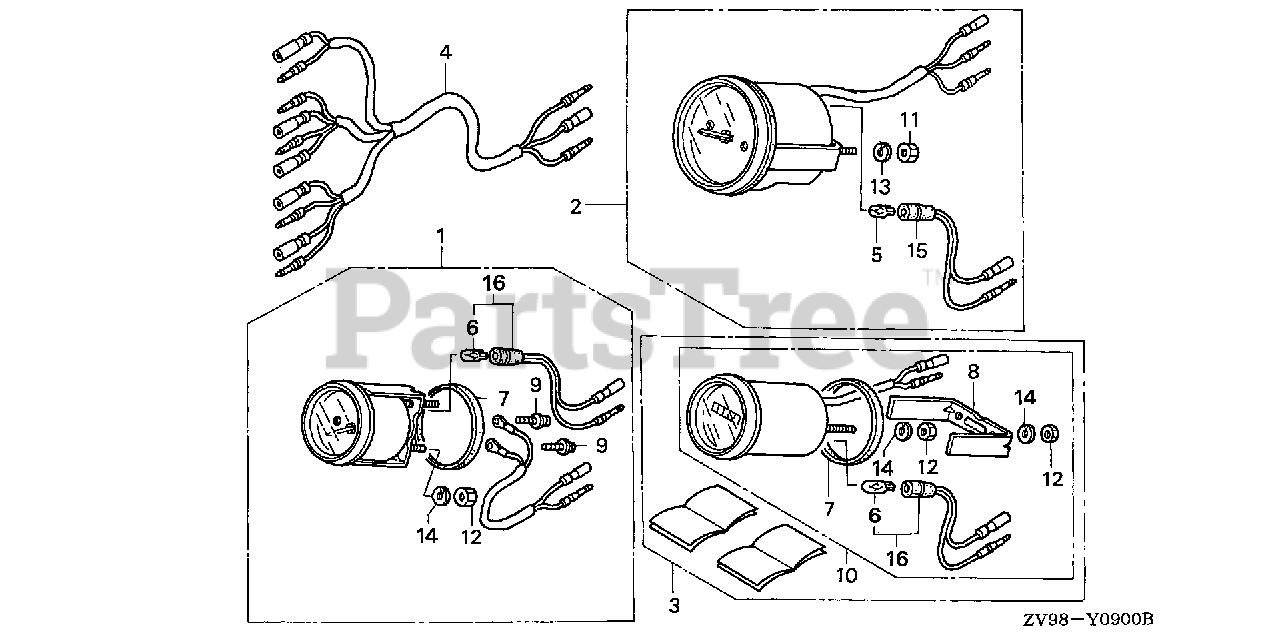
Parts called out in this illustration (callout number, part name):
1	METER KIT, VOLT
1	METER KIT, VOLT (B)
2	METER KIT, TACHO (NOT AVAILABLE)
2	METER KIT, TACHO (B)
3	METER KIT, HOUR (NA USE ALT:39700-ZW5-000ZA)
3	METER KIT, HOUR (B) (NA USE ALT:39700-ZW5-000ZA)
4	HARNESS ASSY., METER (B)
5	BULB, WEDGE BASE (T10) (12V 1.7W) (STANLEY)
6	BULB, WEDGE BASE (12V 1.7W)
7	GASKET
8	BRACKET
9	SCREW-WASHER (3X22)
10	METER ASSY., HOUR
10	METER ASSY., HOUR (B)
11	NUT, HEX. (5MM)
12	NUT, HEX. (4MM)
13	WASHER, SPRING (5MM)
14	WASHER, SPRING (4MM)
15	SOCKET
16	SOCKET
